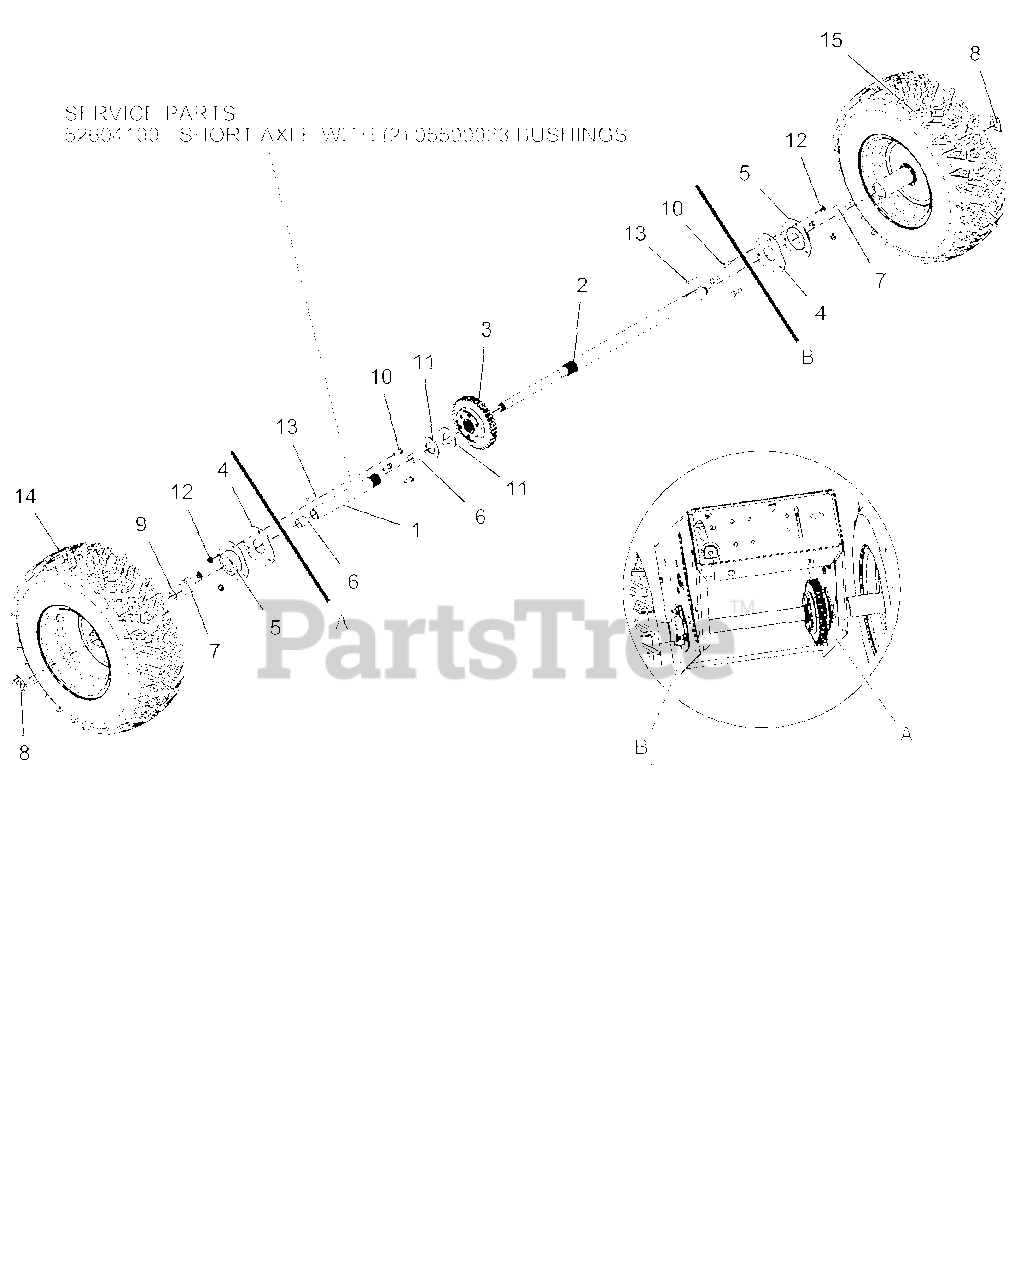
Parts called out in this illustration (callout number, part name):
1	BSHG-SLV .706X.764X.75 BRZ
1	AXLE, SHORT-PRO AUTO DIFF
1	AXLE, SHORT-AUTO W/BUSHINGS
2	AXLE, LONG-PRO AUTO DIFF
3	DIFFERENTIAL, AUTOMATIC
4	PLATE, BEARING SPACER
5	BRG-FLG 1.003/1.000 3 BOLT
6	BSHG-SLV .706X.764X.75 BRZ
7	SPACER, PRO AXLE BEARING
8	CLIP, SNAP .625 DIA
9	RG-RTNG-EXT .625X.042
10	BLT-HEX .25-20X.75 GR5 YWZC
11	WSHR-FL-STL- 1.062X2.0X.134 YZ
12	NUT-LK-CTR-FLG .25-20 YWZC
13	KEY-RECT .25X.188X1.00
14	TIRE/WHEEL,RH 16X6.5-8 DIFF T2
15	TIRE/WHEEL,LH 16X6.5-8 DIFF T2
